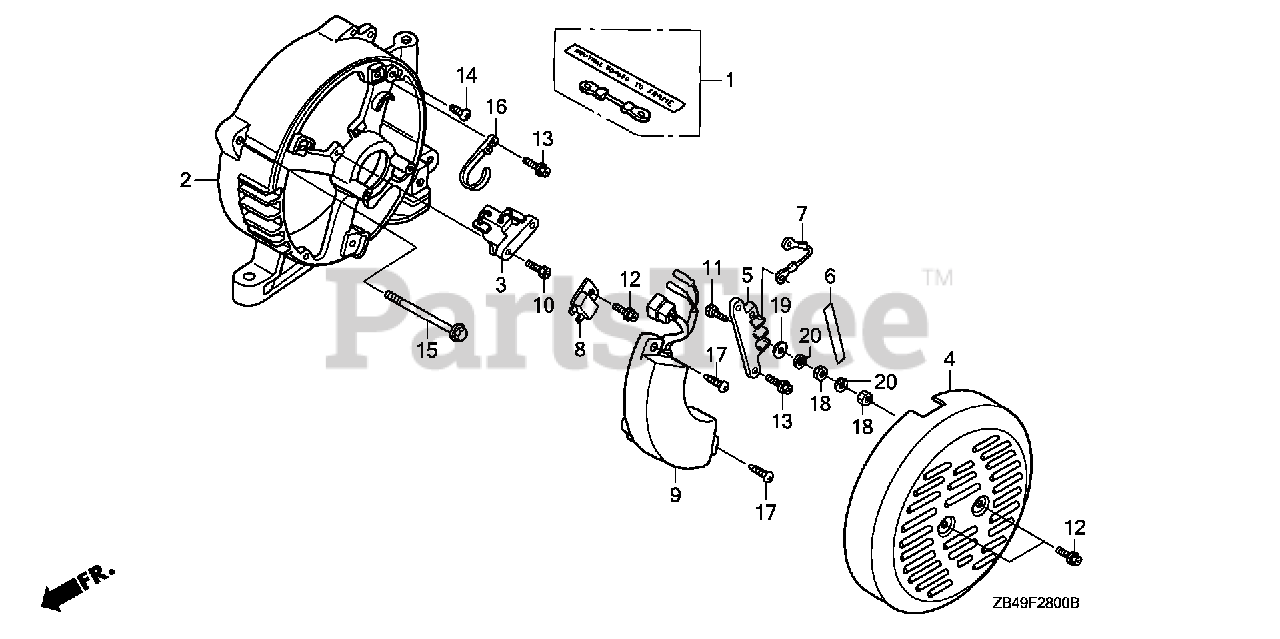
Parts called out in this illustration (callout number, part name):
2	HOUSING, RR. (NA USE ALT:31108-ZB4-631)
3	BRUSH ASSY.
4	COVER, GENERATOR END *NH105* (MAT BLACK)
4	COVER, GENERATOR END *R280* (POWER RED)
5	TERMINAL, VOLT CHANGE
6	MARK, VOLT
8	DIODE, D.C.
9	REGULATOR ASSY., AUTOMATIC VOLTAGE
10	SCREW, TAPPING (5X18)
11	BOLT, HEX. (5X20)
12	SCREW, TAPPING (5X12)
13	SCREW, TAPPING (5X14)
14	SCREW, PAN (5X12)
15	BOLT, FLANGE (6X120)
16	TIE, CABLE
17	SCREW, TAPPING (5X16)
18	NUT, HEX. (5MM)
19	WASHER, PLAIN (5MM)
20	WASHER, SPRING (5MM)
